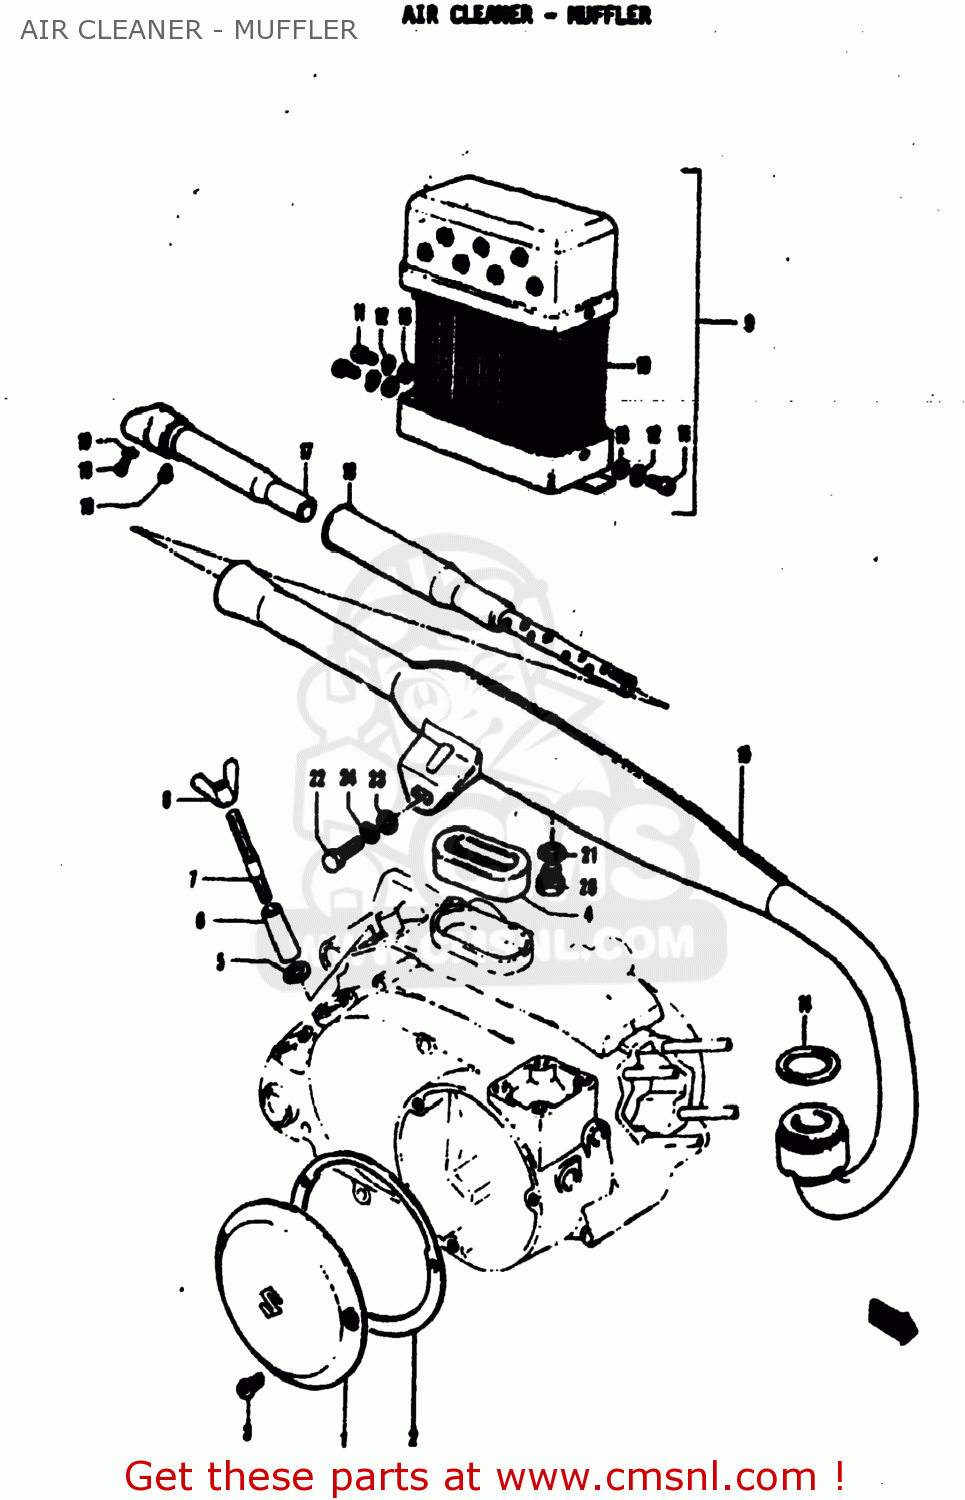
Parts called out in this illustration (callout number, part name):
2	GASKET,CARB INSPECTION CAP (NAS)
3	SCREW
5	WASHER
6	SPACER (6.8X10X20)
7	STUD 6X30
8	NUT
10	FILTER,AIR CLEANER
11	SCREW
12	LOCK WASHER
13	WASHER
14	GASKET,EXHAUST PIPE (MCA)
18	SCREW(5X6)
19	LOCK WASHER
20	BOLT 10X9
21	GASKET(10X14X3.6) (NAS)
22	BOLT
23	WASHER
24	LOCK WASHER
